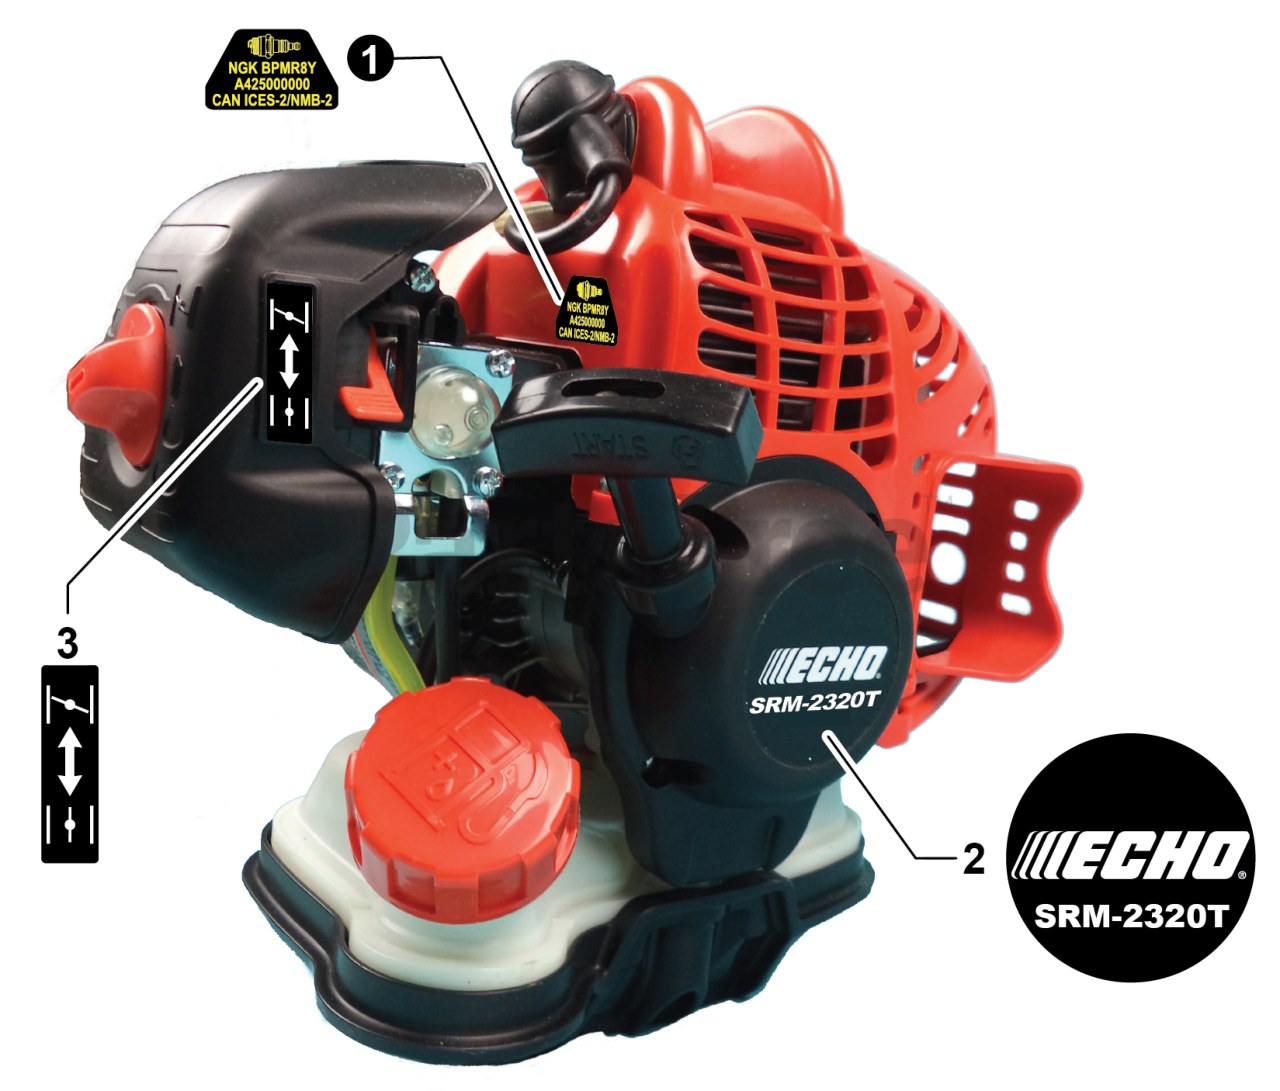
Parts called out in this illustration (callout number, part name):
1	LABEL - SPARK PLUG - BPMR8Y
2	LABEL - RECOIL STARTER - SRM-2320T
3	LABEL - CHOKE
